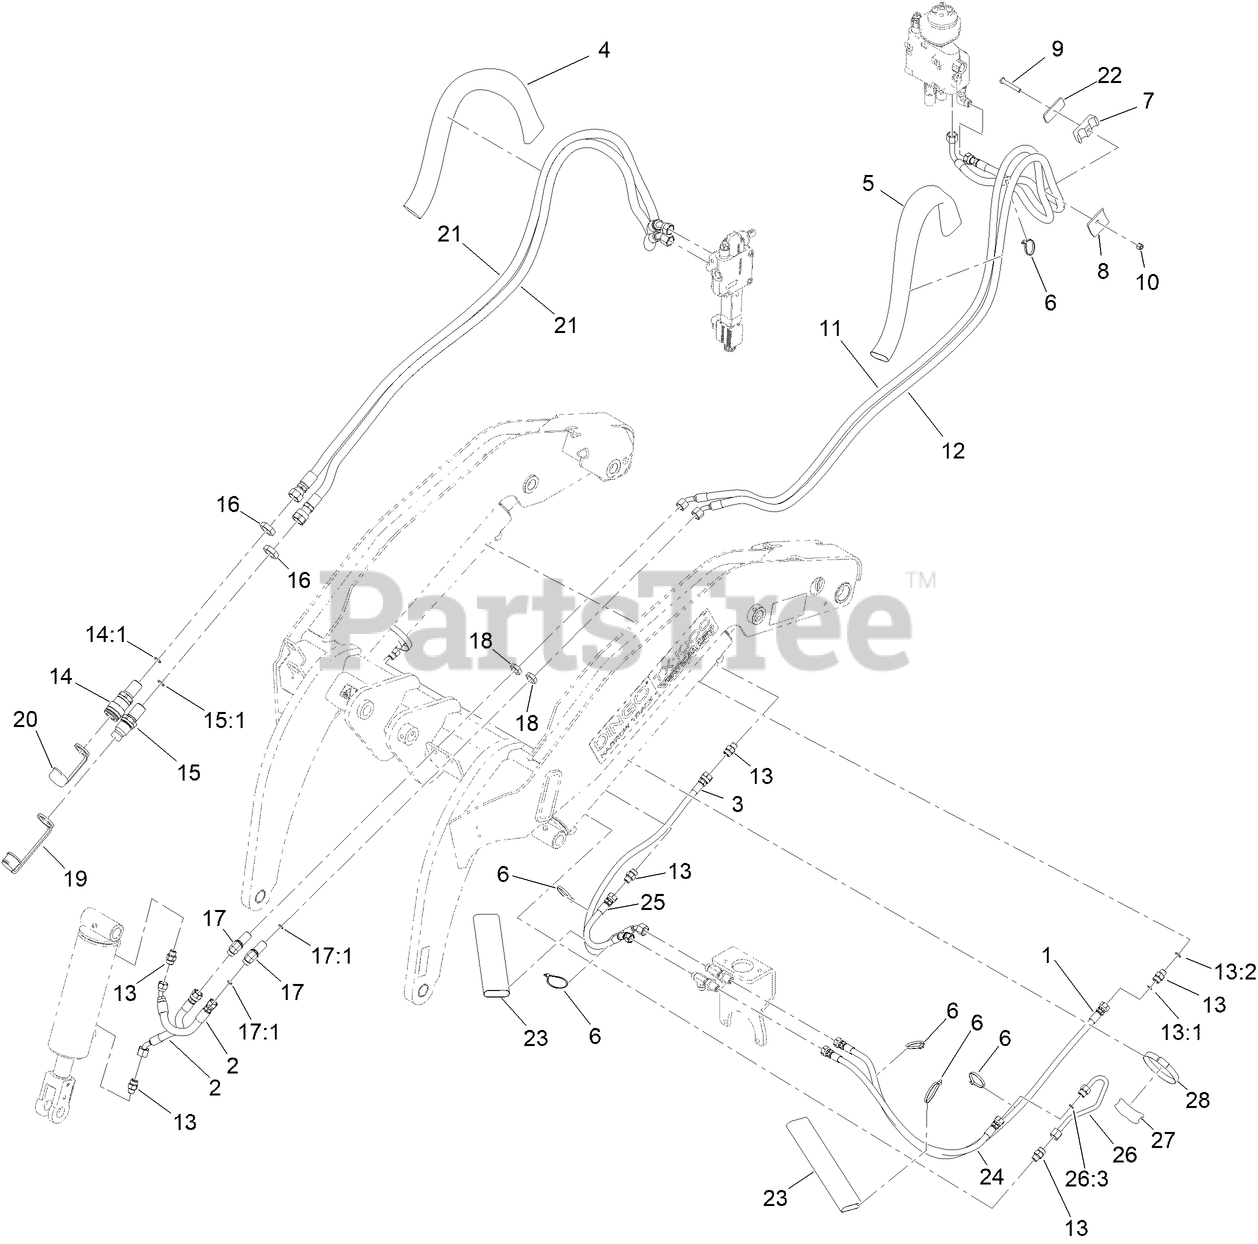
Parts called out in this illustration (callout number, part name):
1	HOSE ASM
2	HYD HOSE ASM
3	HOSE ASM
4	SLEEVE-PROTECTIVE
5	SLEEVE-PROTECTIVE
6	TIE-CABLE
7	CLAMP-TUBE
8	PLATE-HOLDDOWN, HOSE
9	BOLT-TAP, HH
10	NUT-LOCK, NI
11	HYD HOSE ASM
12	HYD HOSE ASM
13	FITTING-STRAIGHT
13:1	O-RING
13:2	O-RING
14	BULKHEAD COUPLER ASM
14:1	O-RING
15	BULKHEAD NIPPLE ASM
15:1	O-RING
16	NUT-LOCK, BULKHEAD
17	ELBOW-BULKHEAD, 45 DEG
17:1	O-RING
18	NUT-LOCK
19	CAP-DUST, NIPPLE
20	CAP-DUST, COUPLER
21	HYD HOSE ASM
22	PLATE-CLAMP, HOSE
23	SLEEVE-PROTECTIVE
24	HOSE ASM
25	HOSE ASM
26	TUBE-HYD
26:3	O-RING
27	BLOCK-HARDLINE
28	CLAMP-BAND/SCREW
